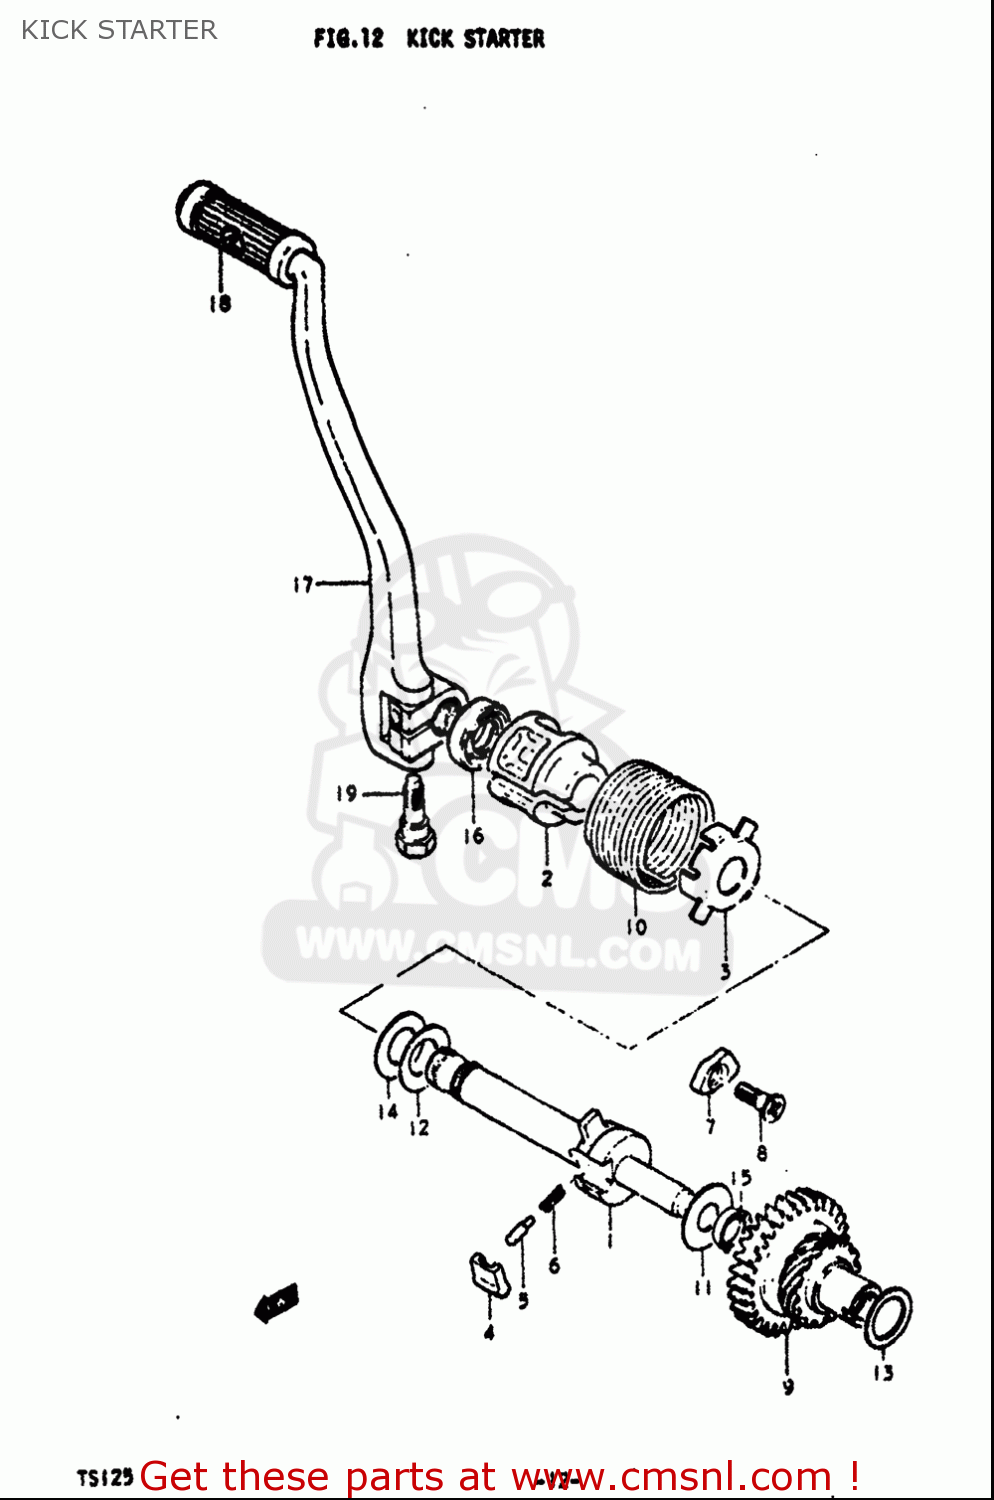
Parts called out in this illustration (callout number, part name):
2	GUIDE,KICK SHAFT SPRING
3	HOLDER,KICK SHAFT SPRING
4	PAWL,KICK STARTER
5	PIN(5X15.5)
6	SPRING
7	LIFTER,KICK STARTER PAWL
8	SCREW(6X19)
9	GEAR,KICK STARTER DRIVE
10	SPRING
11	WASHER
12	WASHER(16X30X0.5)
13	SHIM(20X28X1)
14	WASHER
15	OIL SEAL
16	SEAL,OIL(16X30X8)
17	LEVER ASSY,KICK STARTER
18	RUBBER,KICK STARTER PEDAL
19	BOLT
